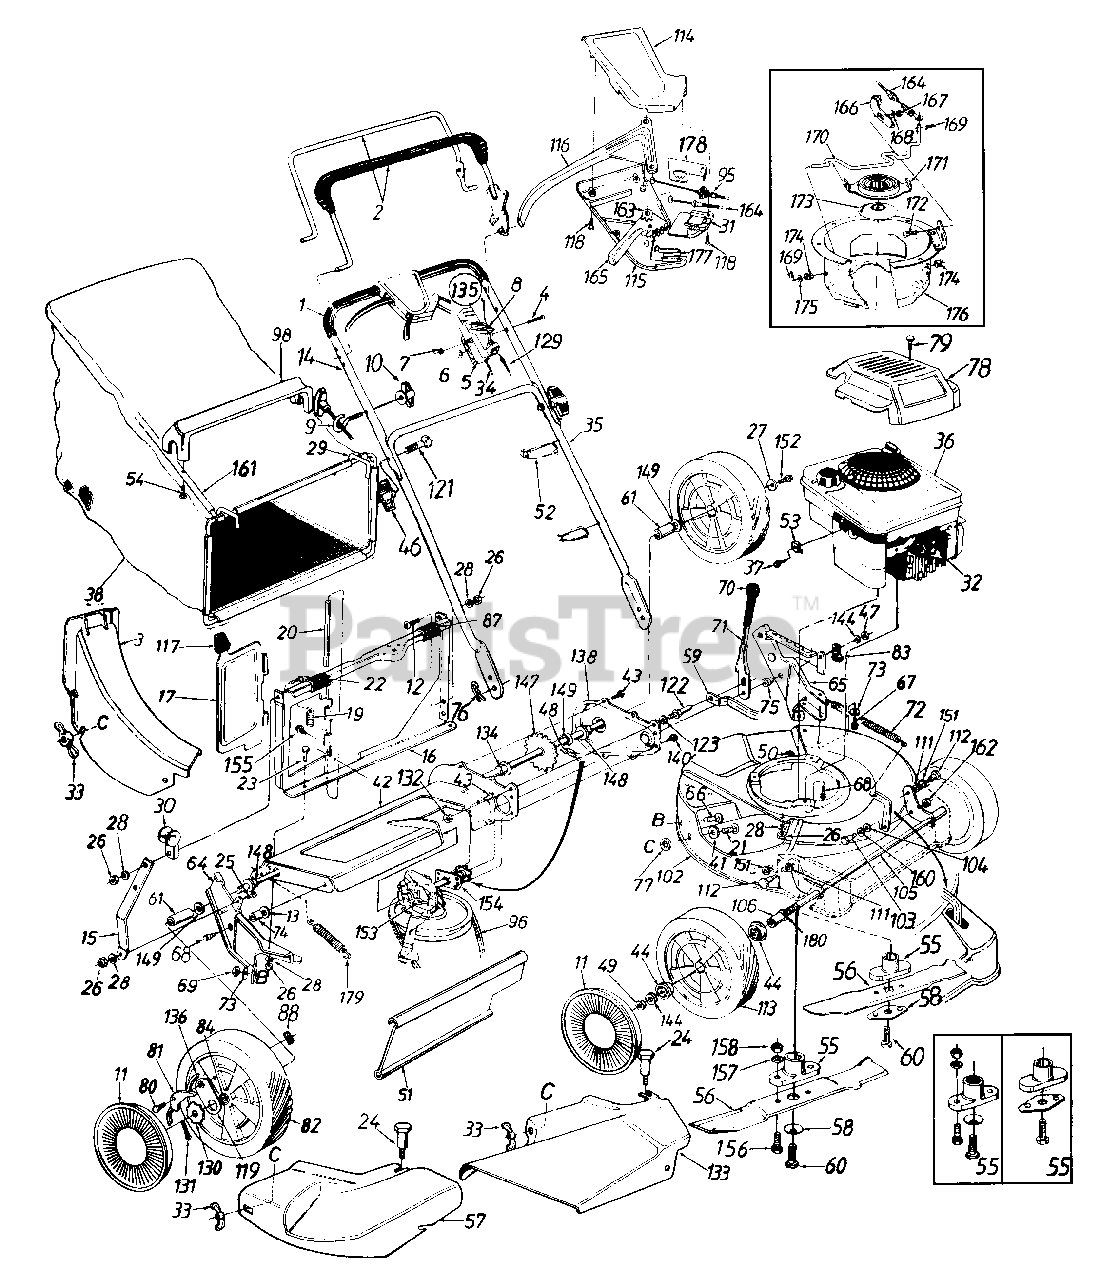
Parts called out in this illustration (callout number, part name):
1	Foam Grip
2	Control Handle Ass'y.
3	Rear Discharge Chute Ass'y.
4	Oval C-Sunk Scr.
5	Throttle Body
6	Spr. Wash. .66" I.D.
7	Hex L-Nut 1/4-20 Thd.
8	Throttle Lever
9	Rope Guide
10	Handle Knob 1/4-20 Thd.
11	Gray (3-1/2" Dia.)
11	Gray (5-1/2" Dia.)
11	Yellow (5-1/2" Dia.)
12	Truss Mach. Scr. 1/4-20 x .62" Lg.
13	FL-Wash. .383" I.D. x 1" O.D.
20	Pivot Pin
21	Carriage Bolt 1/4-20 x .62"
22	Truss Mach. Scr. 1/4-20 x 3/4" Lg.
23	Hex AB-Tap Scr. 1/4 x .38" Lg.
24	Shoulder Bolt .312 Dia. x .18 Lg.-Special
25	Hex Bolt 1/4-20 x .62" Lg.
26	Hex Nut 1/4-20 Thd.
27	Bell-Wash. 1/4" I.D.
28	L-Wash. 1/4" I.D.
30	Rope Guide
31	S.P. Control Cover
32	Spark Plug Insulator
33	Wing Nut w/Washer
34	Throttle Control Wire 61"
36	Engine
37	Hex Self-Tap Scr. #10-32 x .62" Lg.
38	Grass Bag (Plain)
38	Grass Bag w/Logo
41	FL-Wash. .344" I.D. x .62"
44	Ball Bearing
46	Hand Knob
47	Hex Patch L-Nut 3/8-24 Thd.
48	#48 Chain .500" Pitch x 30 Links
49	Hex L-Nut 1/2-20 Thd.
51	Rear Flag 4.8" x 18" Lg.
52	Cable Tie
53	Cable Clamp
54	Hex AB Scr. #12 x 1.25" Lg.
55	Blade Adapter Kit (Splined)
55	Blade Adapter Kit (Keyed)
56	21" Mulching Blade
57	Mulching Plug
58	Bell-Wash. .46" I.D.
58	Blade Belt Support
59	Height Adj. Connecting Arm
60	Hex Bolt 7/16-20 x 1.5" Lg.
60	Hex Bolt 3/8-24 x 1.5" Lg.
61	Spacer .513" I.D. x .703" O.D. x .69" Lg.
63	L-Wash. 5/16" I.D.
64	R.H. Handle Wheel Brkt. Ass'y.
65	L.H. Handle Wheel Brkt. Ass'y.
66	Carriage Bolt 5/16-18 x .62."
67	Hex Wash. Hd. B-Tap Scr. 5/16-18
68	Hex Wash. Hd. TT-Tap Scr. 3/8-16.
69	Hex Nut 5/16-18 Thd.
71	Height Adj. Lever
72	Extension Spring .75" O.D. x 8" Lg.
73	Bell-Wash. 5/16" I.D.
74	Spacer
75	Shld. Spacer .500" Dia.
76	Hairpin Clip
77	Bolt Retainer 1/4 x .50" O.D.
78	Engine Shroud
78	XTE Engine Shroud
79	Screw #10 x 1.25" Lg.
80	Shld. Scr. .342" Dia. x .268
81	Pawl
81	RH Pawl
82	Rear Wheel Ass'y. Comp.
83	Clamp
84	Bearing 1/2" I.D.
87	Panel Clip
88	Weld L-Nut 1/4-20 Thd.
95	S.P. Cable
96	V-Belt
97	Hex AB-Tap Scr. 1" Lg.
98	Bag Handle
102	21" Deck Ass'y.
103	Shld. Bolt .5" Dia. x .295
104	Bell-Wash. .515" I.D. x 1.0" O.D
105	Front Axle Ass'y.
106	Sleeve .526" I.D. x .690" O.D. x .
111	Intern. L-Wash. 3/8 I.D.
112	Shld. Bolt .575" Dia. x .42
113	Front Wheel Ass'y. Comp. (Gray Rim)
113	Front Wheel Ass'y. Comp. (Yellow Rim)
114	Self-Propelled Control Cover
115	Self-Propelled Control Cover
116	Control Lever
117	Door Grip
118	FL-"C"-Sunk Hd. Tap Scr. #10 x .75"Lg.
119	Pawl Plate
121	Curved Hd. Bolt 5/16-18 x 2" Lg.
122	Shld. Pin 1/8" Dia. x 1.00" Lg.
123	L-Wash. 3/8" I.D.
129	Control Cable 43" Lg.
130	Ratchet Wheel 1.62" O.D.
131	Cotter Pin 1/8" Dia. x 1.00" Lg.
132	Hex Jam Nut 3/8-24 Thd.
133	Side Chute Deflector Ass'y.
134	Hex Flange Bearing
135	Throttle Box Comp.
136	Spring-Nylon
144	FL-Wash. .385" I.D. x .87"
147	Rear Shaft Ass'y. 21.94" Lg.
148	Hex Flange Bearing .506" I.D. Plastic
149	FL-Wash. .531" I.D. x .930"
151	Flanged Nyliner Brg.
152	Hex Bolt 1/4-20 x .62" Lg. (Grade 5)
153	Transmission Comp.
154	Hex Bearing Cup
155	Hex B-Tap Scr. #10 x .38
156	Hex Scr. 3/8-24 x 1.0" Lg.
157	L-Wash. 3/8" I.D.
158	Hex Nut 3/8-24 Thd.
160	FL-Wash. .51" I.D. x .75" O.D
162	Hex Jam Nut 3/8-16 Thd.
163	3 Tooth Rack Gear Insert
164	Spd. Control Cable-50" Lg.
165	6-Spd. Shift Lever
168	Hex Cent. L-Nut 1/4-20 Thd.
169	Shift Rod
170	Shift Rod
171	Movable Pulley Half Ass'y.
172	Carr. Bolt 1/4-20 x .50" Lg.
173	Spined Pulley Half
174	Flanged Bushing
175	FL-Wash. .328" I.D. X .68" O.D.
178	6-Speed Rack Cable Brkt.
179	Ext. Spring 3.8" Lg.
180	FL-Wash. .385 ID
